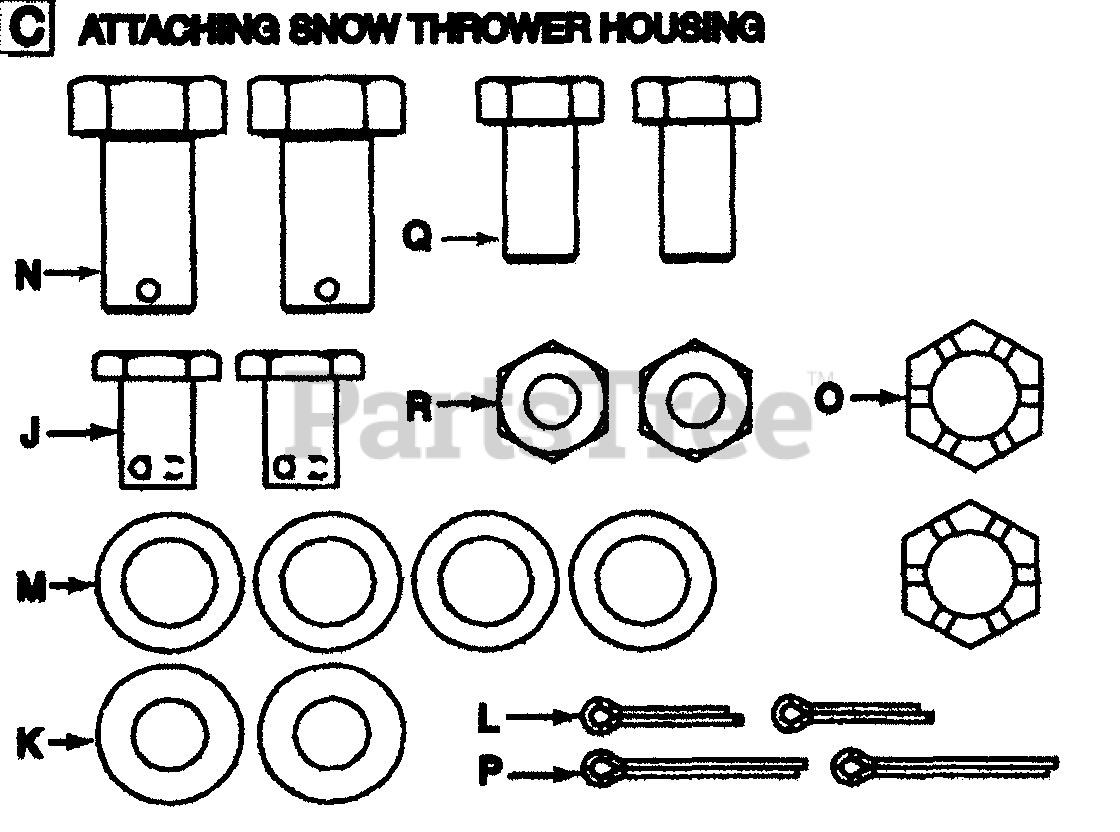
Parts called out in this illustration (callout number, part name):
J	Lift Pins
K	Flat Washers 1/2" I.D. x 1" O.D.
L	Cotter Pins .75" Long
M	Flat Washers 5/8" I.D. x 1" O.D.
N	Hex Bolts 5/8-18 x 1.25" Long
O	Hex Slotted Nuts 5/8-18 Thread
P	Cotter Pins 1.25" Long
Q	Hex Bolts 1/2-13 x 1" Long
R	Hex Lock Nuts 1/2-13 Thread
